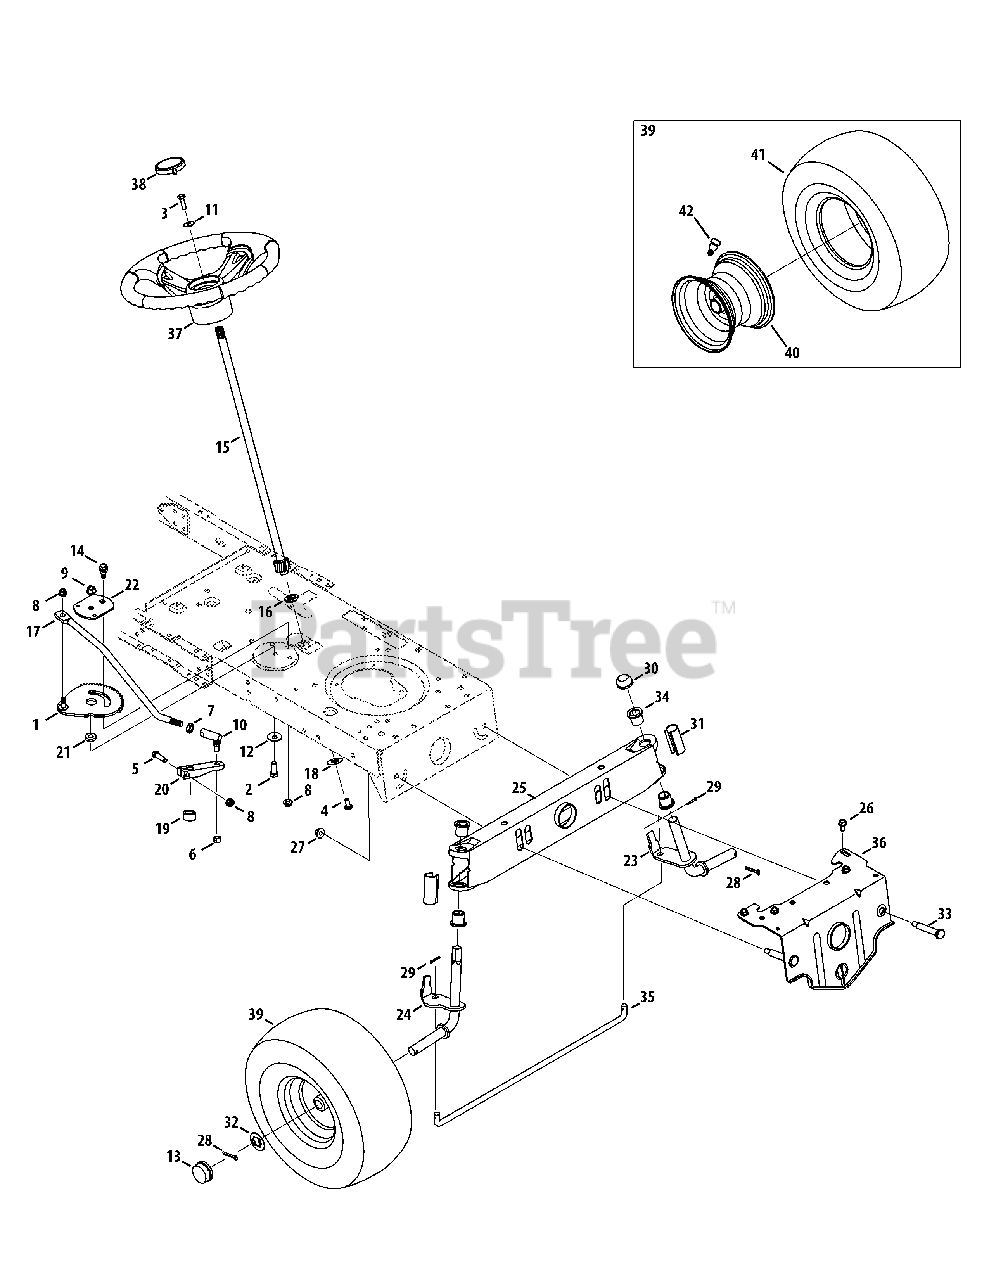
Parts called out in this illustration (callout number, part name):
1	Gear Assembly, Steering
2	Hex Head Screw, 3/8-16 x 1.00
3	Screw, 5/16-18, 1.00, Gr5, Lock
4	Screw, Mach, 5/16-18, 0.750
5	Screw, 5/16-18, 1.75, Gr5
6	Nut, Jam Lock, 3/8-24
7	Nut, Jam, 7/16-20, Gr2
8	Nut, Flange Lock, 5/16-18, Grf
9	Nut, Flange Lock, 3/8-16, Grf
10	Ball Joint, 7/16-20, Lock
11	Washer, Bell, .340 x .872 x .060
12	Bevel Washer, .390 x 1.130 x .062
13	Hub Cap
14	Shoulder Screw, 5/16-18
15	Steering Shaft, 5/8 Spline
16	Bearing, Flange, Hex 5/8
17	Drag Link, Steering
18	Cap, 1.25 x .16
19	Spacer, .710 ID x .125 OD x .56
20	Steering, Block
21	Spacer, .38 x .854 x .20
22	Stabilizer Gear Plate
23	Axle Assembly LH
24	Axle Assembly RH
25	Pivot Bar Axle Assembly
26	Screw, 5/16-18, 0.750
27	Nut, Flange Lock, 3/8-16, GrF
28	Pin, Cotter, 5/32, 1.25
29	Pin, Cotter, 1/8 x 0.75
30	Push Cap, 3/4
31	Axle Cap
32	Washer, Flat, .781 x 1.59
33	Screw, Shlder, .500 x 2.380, 3/8-16
34	Flange Bearing
35	Tie Rod
36	Pivot Bar Bracket
37	Steering Wheel, Standard Grip
38	Cap, Steering Wheel (Crafts. logo)
39	Wheel Assembly
41	Tire, 15 x 6 x 6 Rd. Shoulder
42	Valve Stem
